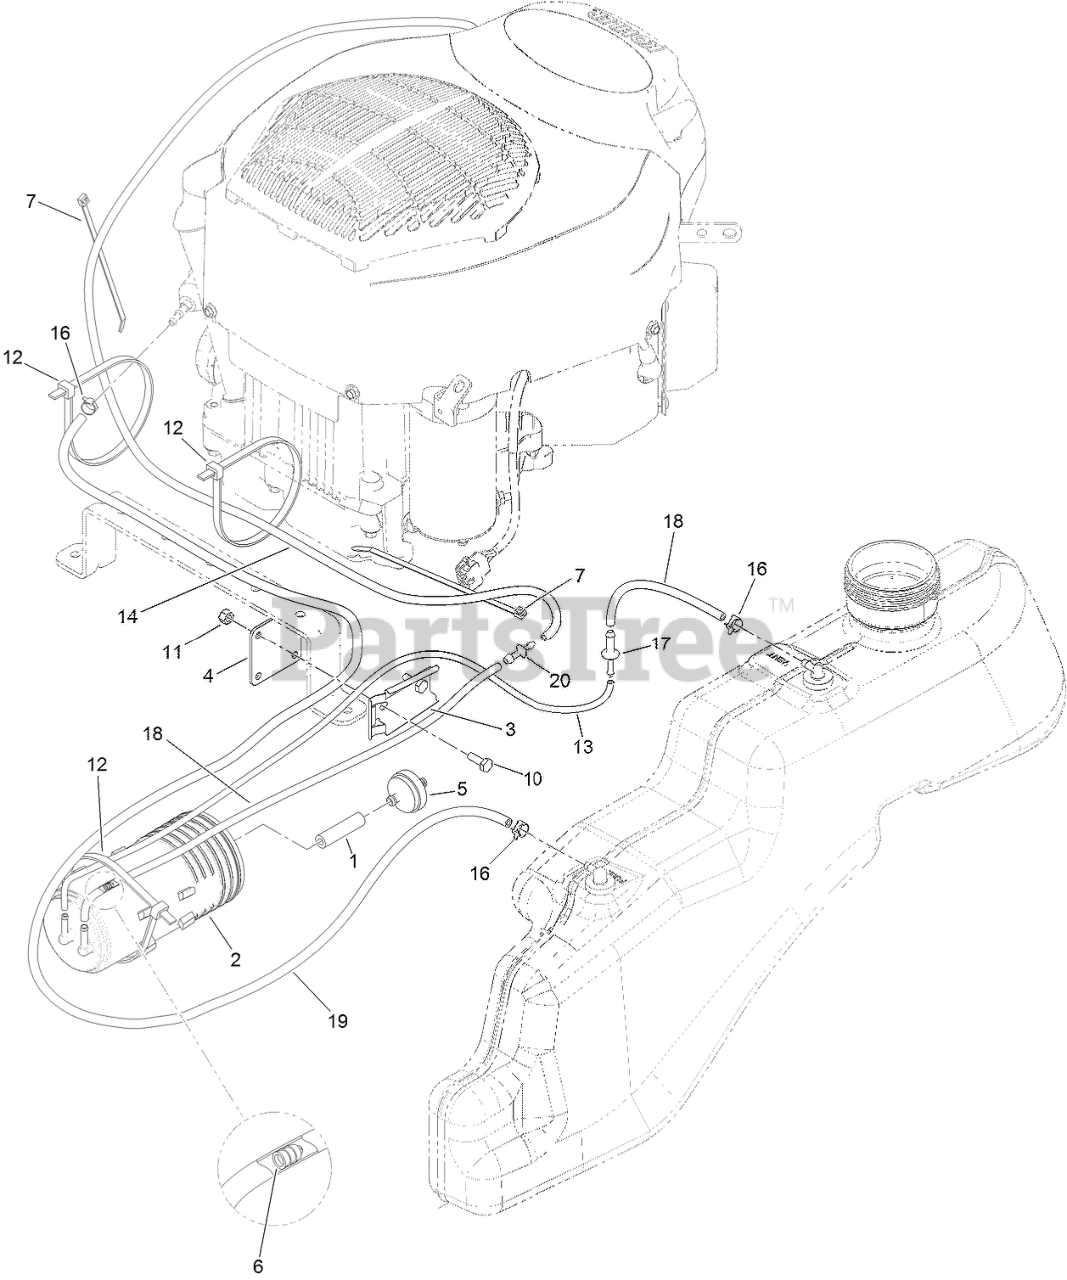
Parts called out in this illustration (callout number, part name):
1	HOSE-FUEL
2	CANISTER-CARBON, 800CC
3	BRACKET-CANISTER, CARBON
4	PLATE-ADAPTER
5	FILTER-FUEL, INLINE
6	CARTRIDGE-VALVE, CHECK
7	TIE-CABLE
10	SCREW-HH
11	NUT-LOCK, NI
12	TIE-CABLE
13	HOSE-FUEL
14	HOSE-FUEL
16	CLAMP-HOSE
17	ADAPTOR-ORIFICE
18	HOSE-FUEL
19	HOSE-FUEL
20	FITTING-STRAIGHT
